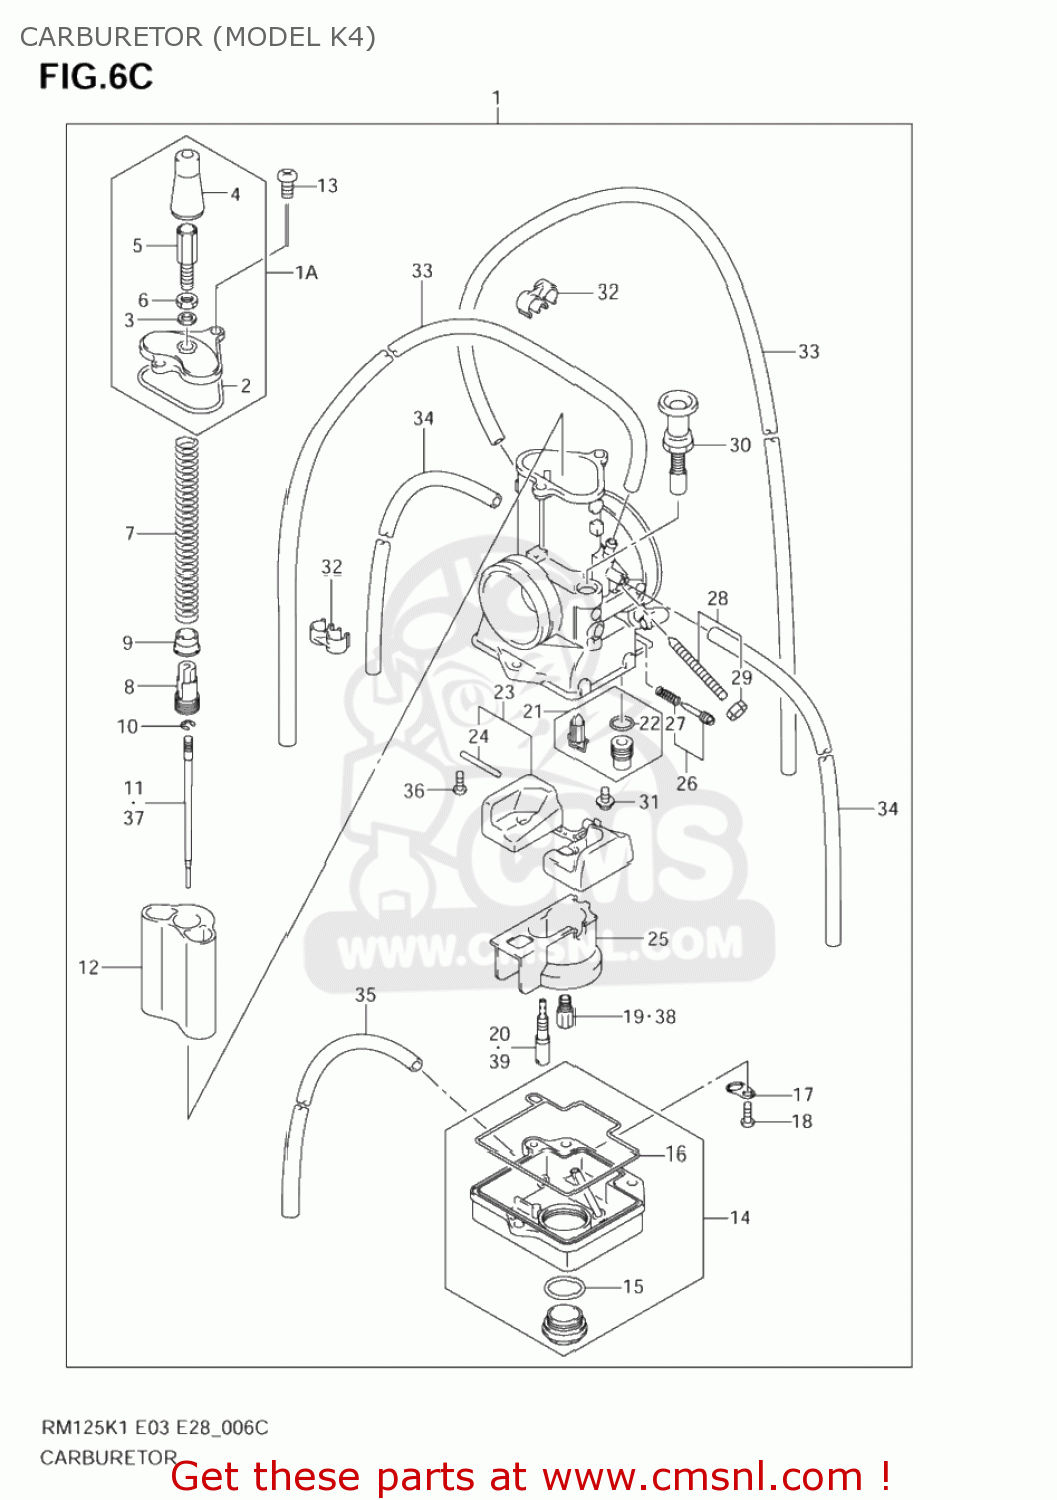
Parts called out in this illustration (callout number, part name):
1	CARBURETOR ASSY
1A	TOP CAP ASSY
2	PACKING (NAS)
3	WASHER,DRAIN PLUG
4	CAP,RUBBER
5	ADJUSTER,CABLE
6	NUT
7	SPRING
8	GUIDE HOLDER
9	RING
10	E RING,MULTIPLE JET NOZZLE
11	NEEDLE(6CHY16-62)
12	VALVE,PISTON
13	SCREW
14	FLOAT BODY ASSY
15	O RING
16	O RING
17	PLATE,CARBURETOR
18	SCREW(5X14)
19	JET,MAIN(390)
20	JET,PILOT(42.5)
21	VALVE ASSY,NEEDLE
22	O RING,NEEDLE VALVE SEAT
23	FLOAT SET
24	PIN,FLOAT
25	HOLDER
26	ADJUSTER SET(AS)
27	SPRING
28	ADJUSTER SET (PV)
29	NUT
30	PLUNGER ASSY
31	SCREW
32	CLIP
33	HOSE(3.5X6.5X600)
34	HOSE(3.5X6.5X600)
35	HOSE(3X5X600)
36	SCREW
37	NEEDLE(6CHY17-64)
38	JET,MAIN(400)
39	JET,PILOT(25)
40	WASHER,JET NEEDLE CLIP
41	HOLDER,GUIDE
